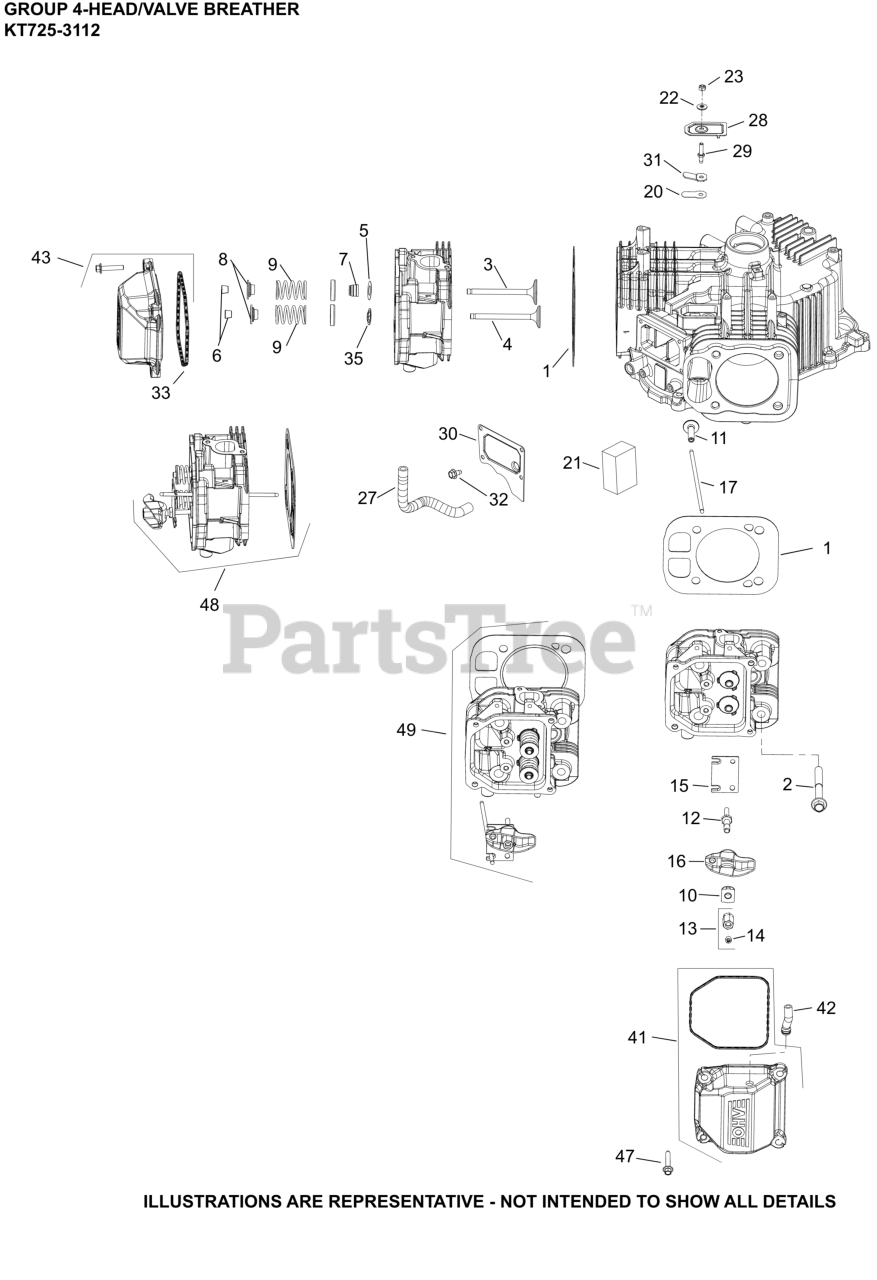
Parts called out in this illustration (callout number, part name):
1	KIT, CYLINDER HEAD GASKET
2	SCREW, HEX FLANGE M10 X 1.5-6g X 90mm
3	VALVE, INTAKE
3	VALVE, INTAKE (.25) - (#2401702S)
4	VALVE, EXHAUST
4	VALVE, EXHAUST (.25)
5	SPACER (.010")
6	KIT, RETAINER
7	SEAL, VALVE BAND
8	CAP, VALVE SPRING
9	SPRING VALVE
10	PIVOT, ROCKER ARM
12	STUD, ROCKER
13	HEX NUT ASSEMBLY
14	SCREW, SET
15	PLATE, GUIDE
16	ARM, ROCKER
17	ROD, PUSH
20	REED, BREATHER
21	FILTER, BREATHER
22	WASHER, SEALING
23	NUT, LOCK M5X.8
27	HOSE, BREATHER
28	COVER, BREATHER REED
30	COVER, BREATHER MEDIA
31	RETAINER, REED
32	SCREW, THREAD FORMING
33	O-RING (YELLOW), VALVE CO
35	RETAINER, VALVE GUIDE (KM)
41	KIT,BREATHER VALVE COVER (PLASTIC)
42	HOSE, FP-USE 32 326 07-S(PLASTIC COVERS)
43	KIT, VALVE COVER-PLAIN (PLASTIC)
47	SCREW, HEX FLANGE (M6 X 31.625 DOG PT)
48	KIT, #1 CYLINDER HEAD
49	KIT, #2 CYLINDER HEAD
